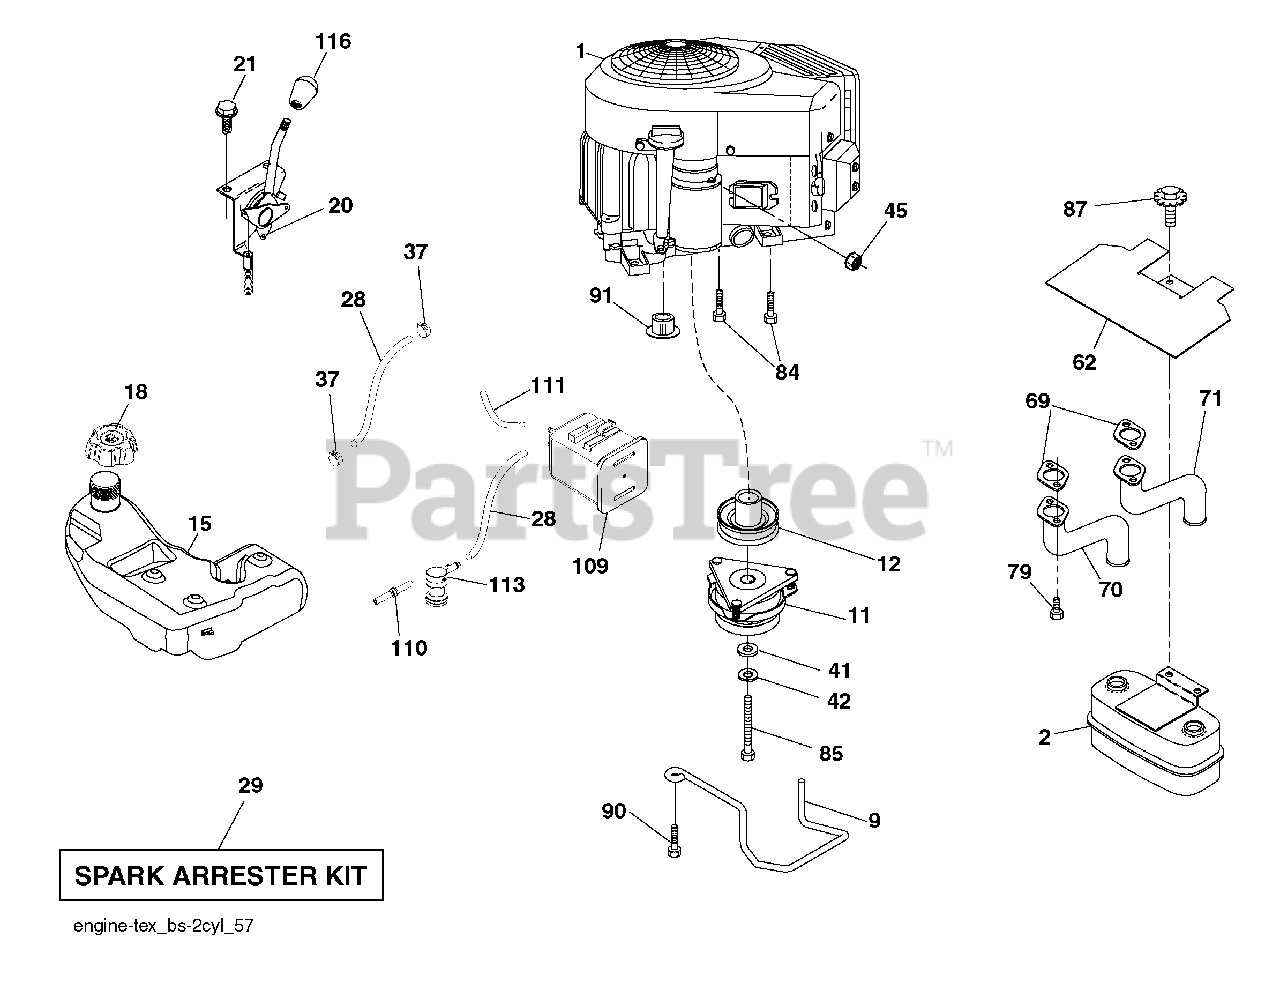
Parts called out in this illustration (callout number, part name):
9	Keeper Belt Engine
11	Clutch Electric
12	Pulley Engine
18	Cap Asm
20	Control Throttle
21	Screw #10 x .750 BOS Thread
28	Fuel Line
29	Spark Arrester Kit
37	Clamp Hose
41	Washer 1-1/2 OD x 15/32 ID x .250
42	Washer Lock 7/16
45	Nut Keps Hex 1/4-20 unc
62	Heat Shield
70	Tube Exhaust
71	Exhaust Tube
79	Screw Socket HP 5/16-18 x 1
84	Screw 3/8-16 x 1-1/4
85	Bolt Hex 7/16-20 x 4 x Gr. 5-1.5 Thr
87	Bolt 5/16-18 unc x 3/4 w/Sems
90	Screw 3/8-16 x 1
91	Bushing 1.375 OD
109	Canister Carbon Filter Asm.
110	Valve Anti Slosh
111	Purge Line
113	Valve Slant Cartrdg
116	Knob Soft Touch
